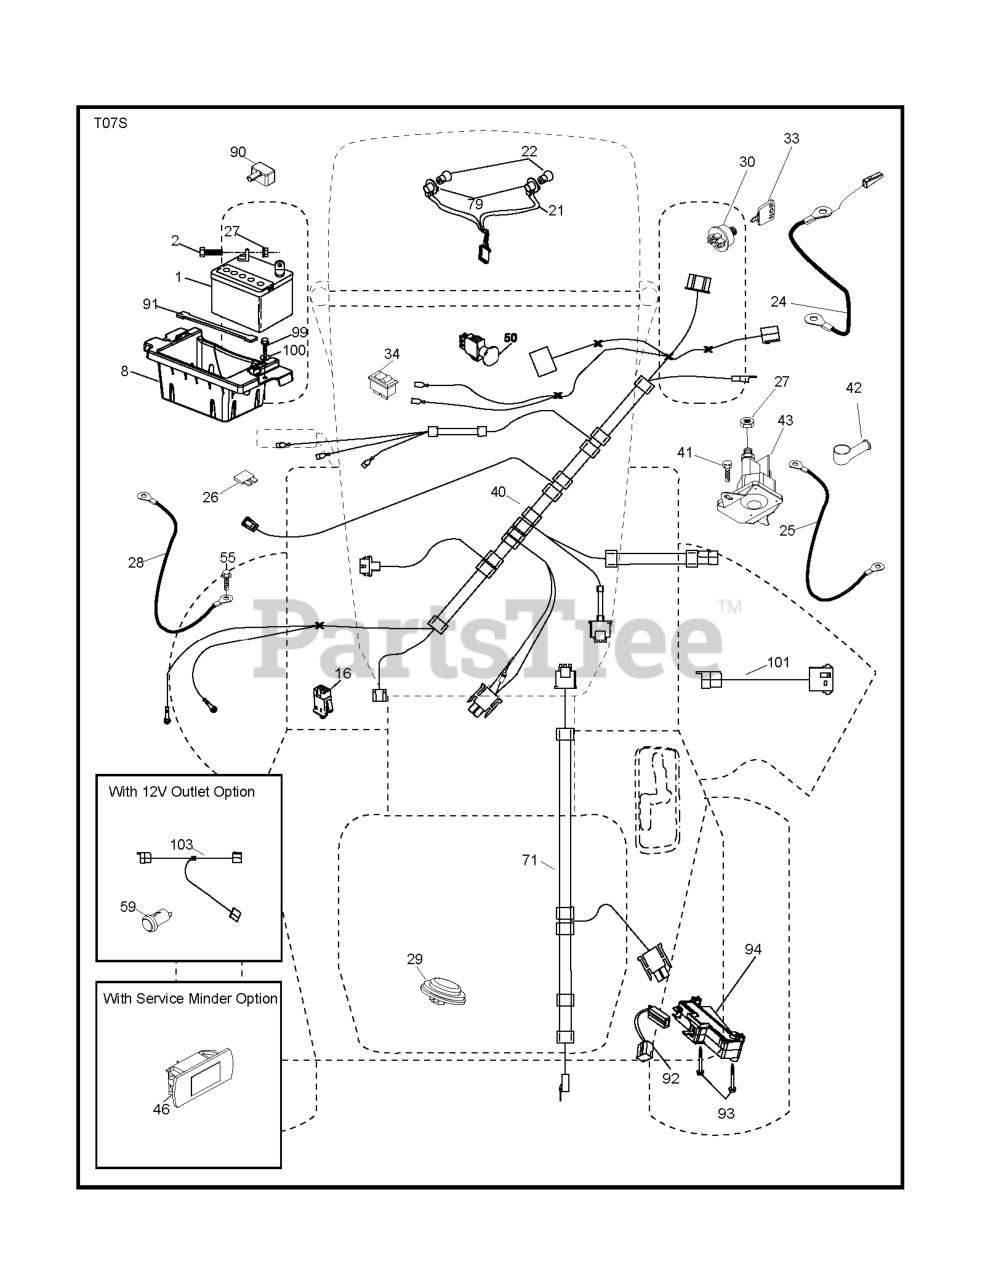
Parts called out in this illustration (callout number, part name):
1	Battery 12 Volt 25 Amp
2	BOLT.HEX.1/4.X.3/4.DICHROMATE
8	BOX.BATTERY.MOUNT.FRONT.LT
16	SWITCH INTERLOOK PUSH-IN
21	HARNESS ASSY LIGHT
24	CABLE.BATT.POS.WIRE.TG.DA SOL
25	CABLE.STARTER.6G.BL/RED.17.5
26	FUSE 20AMP
27	NUT
28	CABLE GROUND 6 GA 21" 90T BLK
29	SWITCH.SEAT.DELTA.OPC.
30	SWITCH.IGN.DELTA.W.LGH.ROS
33	KEY.CHAIN.BLISTER.PACK.GEN.INT
40	HARNESS.IGN.DASH.HUQ/P
41	SCREW
42	TERMINAL COVER
43	SOLENOID.W/BRASS.PLUNGER
50	RP.PTO.SWITCH.8 TERMINAL.BLACK
55	SCREW 5/16"
71	HARNESS-CHASSIS SUB
79	BULB HOLDER ASM.
90	COVER.TERMINAL.BATTERY
91	STRAP.BATTERY.MOUNT.FRONT(2 2)
92	HARNESS.PIGTAIL.CONSLE
93	SCREW.PLASTITE
94	MODULE.REVERSE.ROS
99	SCREW HEXWSHR 1/4-20X3/4
101	PIGTAIL.MATNLK.NEW.HAR
